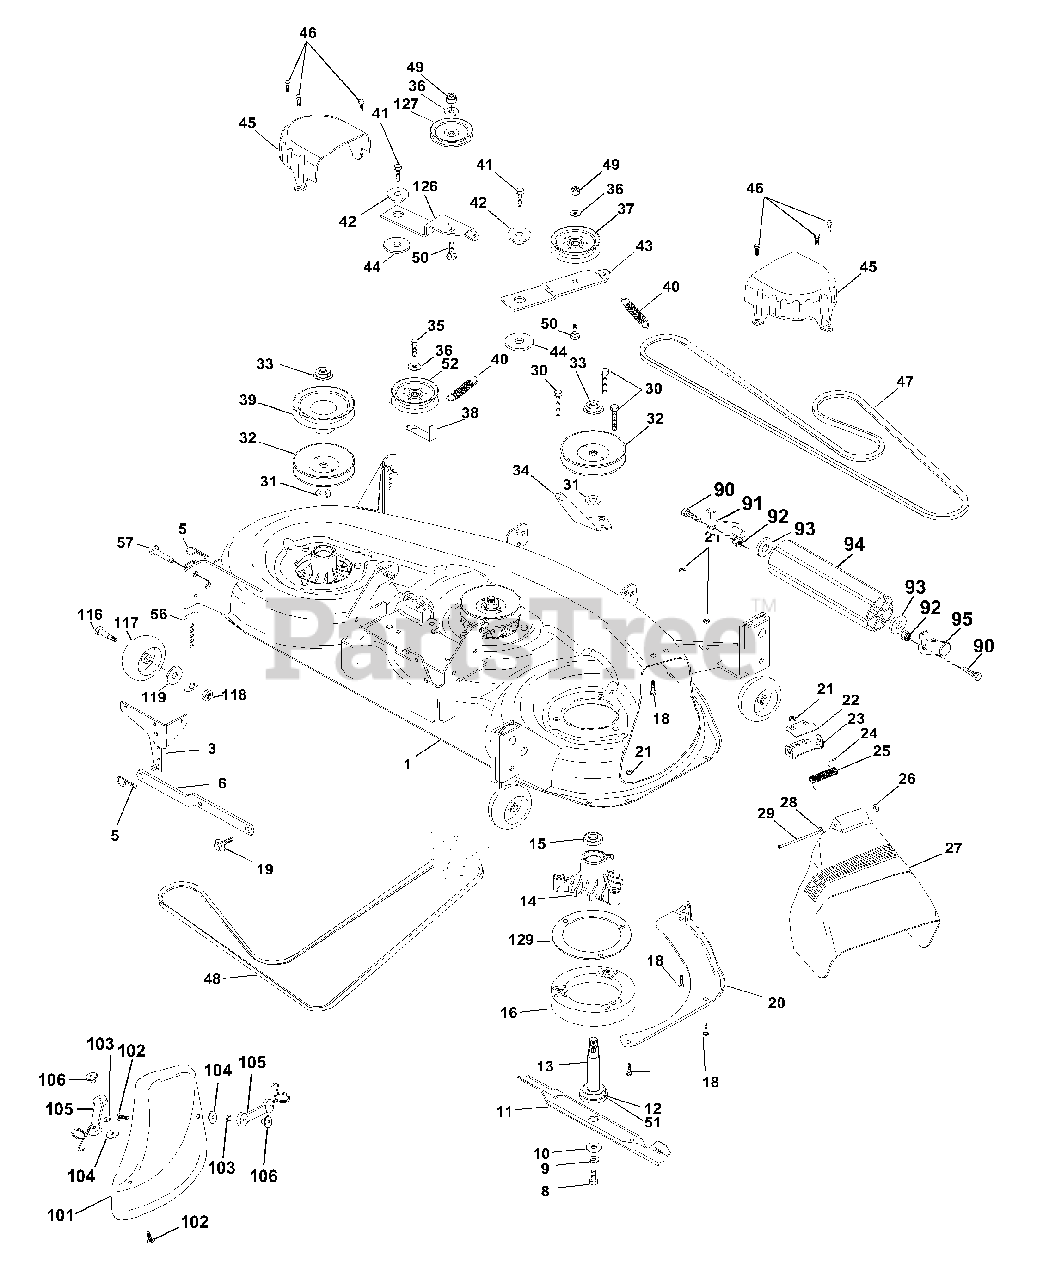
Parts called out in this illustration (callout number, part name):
1	Deck Asm., Mower 46"
3	Bracket Asm., Sway Bar
5	Retainer Spring
6	Arm, Suspension, Rear (Sway Bar)
8	Bolt, Patched 3/8-24 x 1-1/4 Gr. 8
9	Washer, Lock Hvy., Unplated 3/8
10	Washer, Hard Blade, Mower Vented
11	Blade, High Performance
11	Blade, Mulching
12	Bearing, Ball, Mandrel #6204
13	Shaft Asm. w/Lower Bearing
14	Housing, Mandrel
15	Bearing, Ball, Mandrel
16	Stripper, Mower Round
18	Bolt, Carriage 5/16-18 x 5/8
19	Bolt, Hex Head, Shoulder 5/16-18
20	Baffle, Vortex Mower 46"
21	Nut, Crownlock 5/16-18 UNC
22	Stiffiner, Bracket
23	Bracket, Deflector
24	Cap, Sleeve
25	Spring, Torsion, Deflector
27	Deflector Clipping 46" Grey
28	Washer 11/32 x 5/8 x 16 Ga.
29	Rod, Hinge
30	Screw, Thdroll Washer Head
31	Washer, Spacer Mower Vented
32	Pulley, Mandrel
33	Nut, Flg. Top Lock Cntr. 9/16
34	Anchor, Spring Deck 46"
35	Screw thdroll 3/8-16 x 1-3/4 Tytt
36	Washer 13/32 x 13/16 x 16 Ga.
37	Pulley, Idler, Flat
38	Keeper, Belt, Idler
39	Pulley, Idler, Driven
40	Spring, Secondary 44/46/50 Vent
41	Screw, 3/8-16 x 1-1/4 Smgml Tap/R
42	Spacer, Retainer, Mower
43	Arm, Idler Secondary
44	Washer, Hardened
45	Cover, Mandrel Deck
46	Screw, Thdroll. 1/4-20 x 5/8
47	V-Belt, Mower, Secondary
48	V-Belt, Mower, Primary
49	Nut, Crownlock 3/8-16 UNC
50	Bolt, Carriage 3/8-16 x 1-1/2 Gr. 5
51	Washer Felt
52	Pulley Idler 46 Pri Drive 97
56	Bar Adjusting Gauge Wheel
57	Pin Head Rivet
72	Washer 13/32 x 1 x 16 Ga.
90	Bolt, Fin Hex 3/8-16 UNC x 1
91	Bracket Asm. Noseroller, Lh
92	Nut Crownlock 3/8-16 Unc Blk D
93	Washer 17/32 x 7/8 x 16 Ga.
94	Roller Nose 38 & 42
95	Bracket Asm. Noseroller, Rh
101	Cover Mulcher
102	Screw Truss Hd Phil 10-24 x 5/8
103	Washer Lock #10
104	Nut Weld
105	Washer #10
106	Latch Asm Mulch/Bagger
116	Bolt, Shoulder
117	Gauge Wheel
118	Nut, Centerlock 3/8-16 UNC
119	Washer 3/8 x 7/8 x 14 Ga.
126	Arm, Idler, Primary Deck 46"
127	Pulley, Idler, V-Groove Dim. 4.25
129	Reinforcement Mandrell Ring
